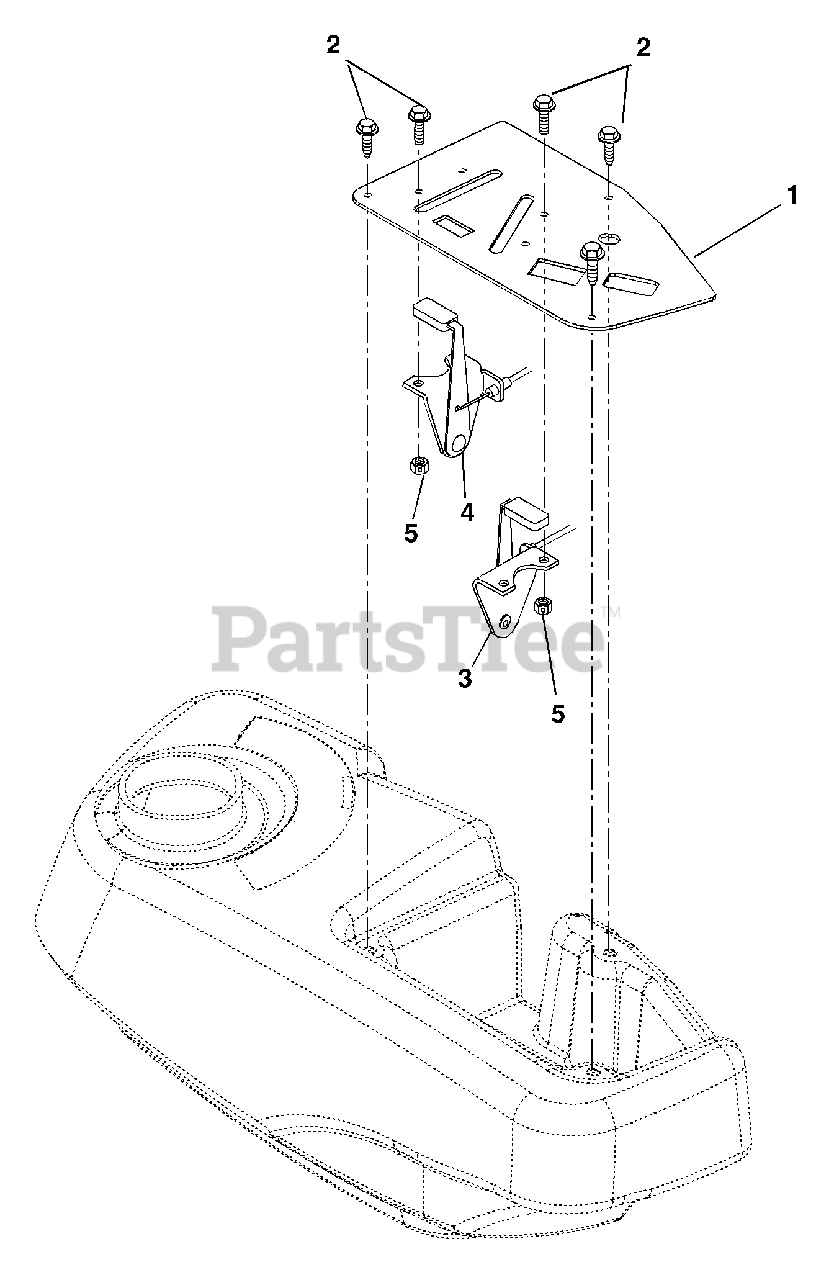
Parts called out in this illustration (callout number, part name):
1	Panel-Control
2	Screw-Machine 10-24 x .50 Hex Washer Head
3	Throttle Control
4	Choke Control
5	Nut-Locking-Nylon 10-24
